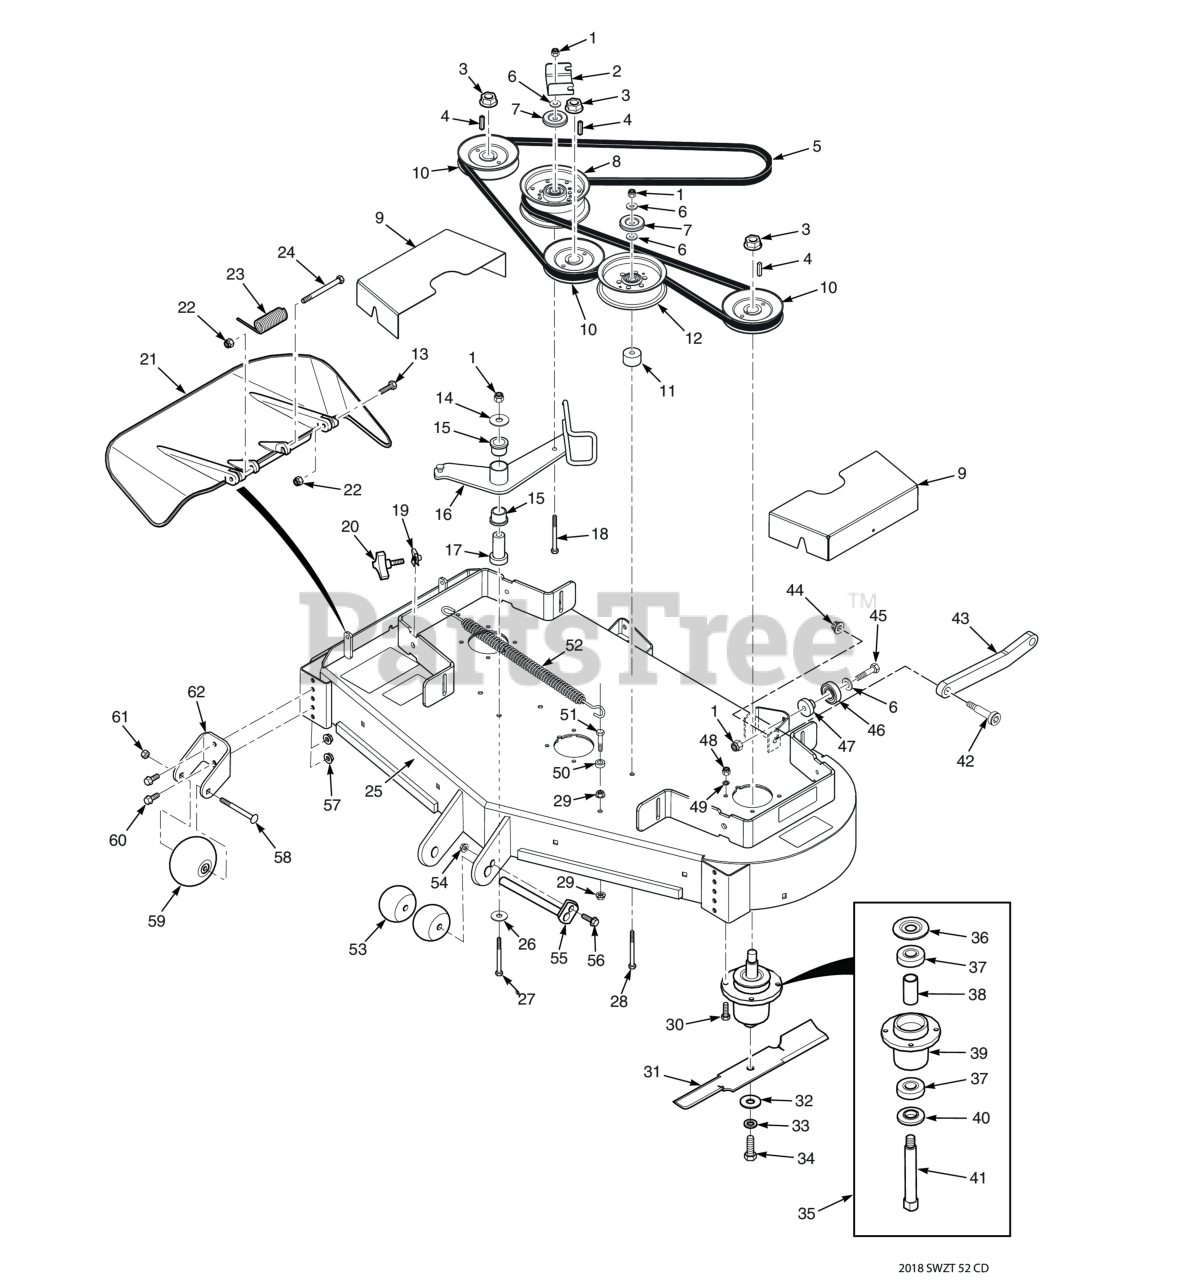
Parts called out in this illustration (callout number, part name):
1	HEX NUT, ELASTIC STOP LOCK, 3/8-16
2	Bracket, Belt Guide
3	Nut, 3/4-16 Spriral Lock
4	Key, 1/4 x 1/4 x 1.25" Pulley Mtg.
5	Belt, Cutter Deck
6	Flatwasher, 3/8 (.391 x .938 x .105 HD) Grade 8
7	Quick Pin, 5/16" Dia.
8	Pulley, Idler 5" Dia.
9	Belt Cover
10	Pulley, 5.73" OD - 25mm Bore
11	Spacer, Idler Pulley
12	Pulley, 5" Idler
13	Bolt, Hex Head 5/16-18 x 1-1/2" - Front
14	Flatwasher, 3/8-.406 x 1-1-1/2 x 7 Gauge
15	Bearing, Plastic
16	Idler Arm (incl. item #15)
17	Pivot, Idler
18	Capscrew, Hex Head 3/8-16 x 3.25"
19	U-Nut, 3/8-16
20	Knob, w/stud 3/8-16 x 1-1/4"
21	Discharge Chute Assy. SFZ52
22	HEX NUT, ELASTIC STOP LOCK, 5/16-18
23	Spring, Discharge Chute
24	Bolt, 5/16-18 x 4-3/4" Hex Head
25	Cutter Deck w/Decals, SMWZT-52
26	Flatwasher, 3/8-.406 x 2.25" x .1875
27	Capscrew, Hex Head 3/8-16 x 3-3/4"
28	Bolt, Hex Head, 3/8-16 x 3-1/2"
29	NUT, 3/8-16 SERRATED FLANGE HEX HEAD
30	Bolt, Hex Head 5/16-18 x 1-1/2" Grade 8
31	Cutter Blade, 18" (52V)
32	Flatwasher, 5/8-.688 x 1-3/4 x .134 HD
33	Lockwasher, 5/8" Spring
34	Bolt, Hex Head 5/8-11 x 1-1/2"
35	Spindle Assembly
36	Debris Shield
37	Bearing
38	Spacer, Bearing
39	Spindle Housing Assembly
40	Protector, Bearing
41	Shaft, Spindle
42	Bolt, Shoulder 1/2 x 3/8-16 x 2-3/4"
43	Pusharm
44	Nut, Flange Elastic Stop Nut, 3/8-16
45	Bolt, Hex Head 3/8-16 x 1-3/4" (Kohler EFI)
46	Bearing
47	Spacer, Bearing
48	Lock Nut, 5/16-18 Elastic Stop Grade 8
49	Lockwasher, 5/16 (.317 x .586 x .078) Helical Spring
50	SPACER, IDLER
51	Bolt, Hex Head 3/8-16 x 1-1/2" Grade 8 Black
52	Spring, L.H. Deck Drive
53	Wheel, Anti-Scalp
54	Nut, Serrated Flange 5/16-18 (Right Front Engine Mounting, Briggs and Kohler Only)
55	Shaft Weldment, Guide Roller
56	Bolt, Heax Head 5/16-18 x 1" (48V / 52V)
57	NUT, 3/8-16 SERRATED FLANGE HEX HEAD
58	Bolt, Hex Head 3/8-16 x 3-1/2"
59	Bolt, Carriage 3/8-16 x 4"
60	Capscrew, 3/8-16 x 1.0" Serrated Flange Hex Hd
61	Bolt, Hex Head 3/8-16 x 1" Ser. Flg.
62	Bracket, Anti-Scalp Wheel
